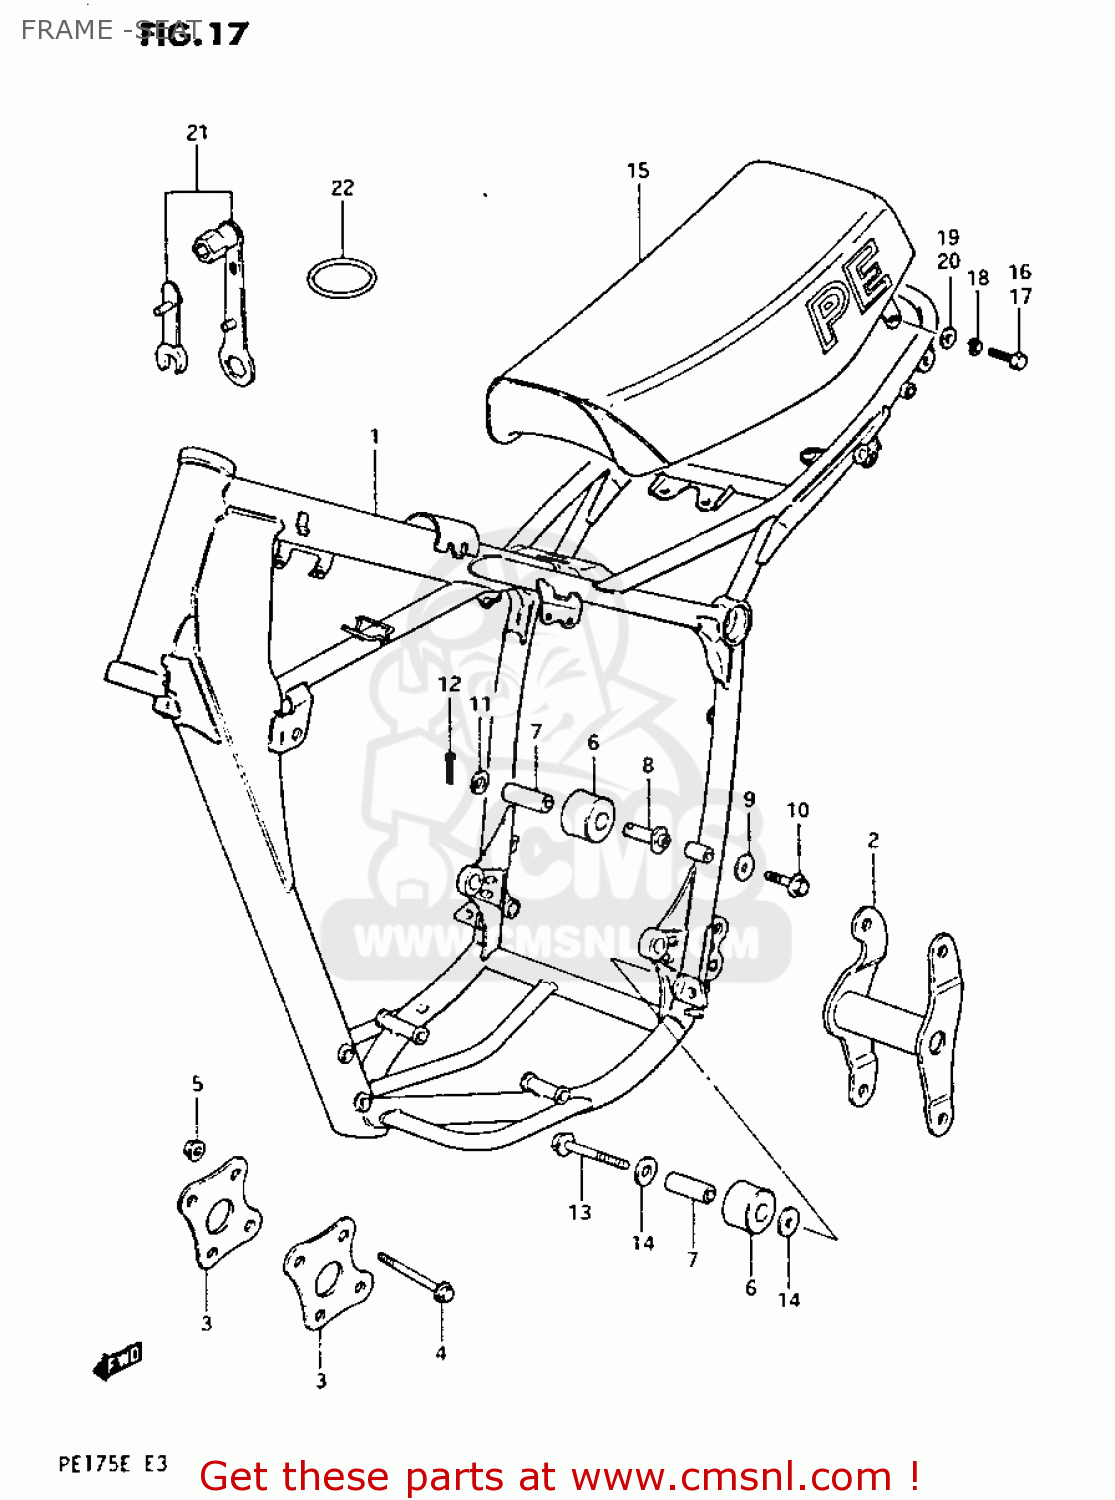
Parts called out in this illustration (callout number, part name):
1	FRAME
2	PLATE,ENGINE MOUNTING
3	PLATE,ENGINE MOUNTING
4	BOLT(8X67)
5	NUT
6	ROLLER,CHAIN LENGTH CONTROL
7	SPACER,CHAIN LENGTH ROLLER
8	BOSS,CHAIN LENGTH ROLLER
9	WASHER
10	BOLT
11	WASHER
12	PIN 25X20
13	BOLT(8X41)
14	WASHER
15	SEAT ASSEMBLY
16	BOLT
17	BOLT 8X40
18	LOCK WASHER
19	WASHER (8.5X20X2.6)
20	WASHER (8.7X22X2)
21	SPARK PLUG WRENCH
22	O RING TOOL FITTING
